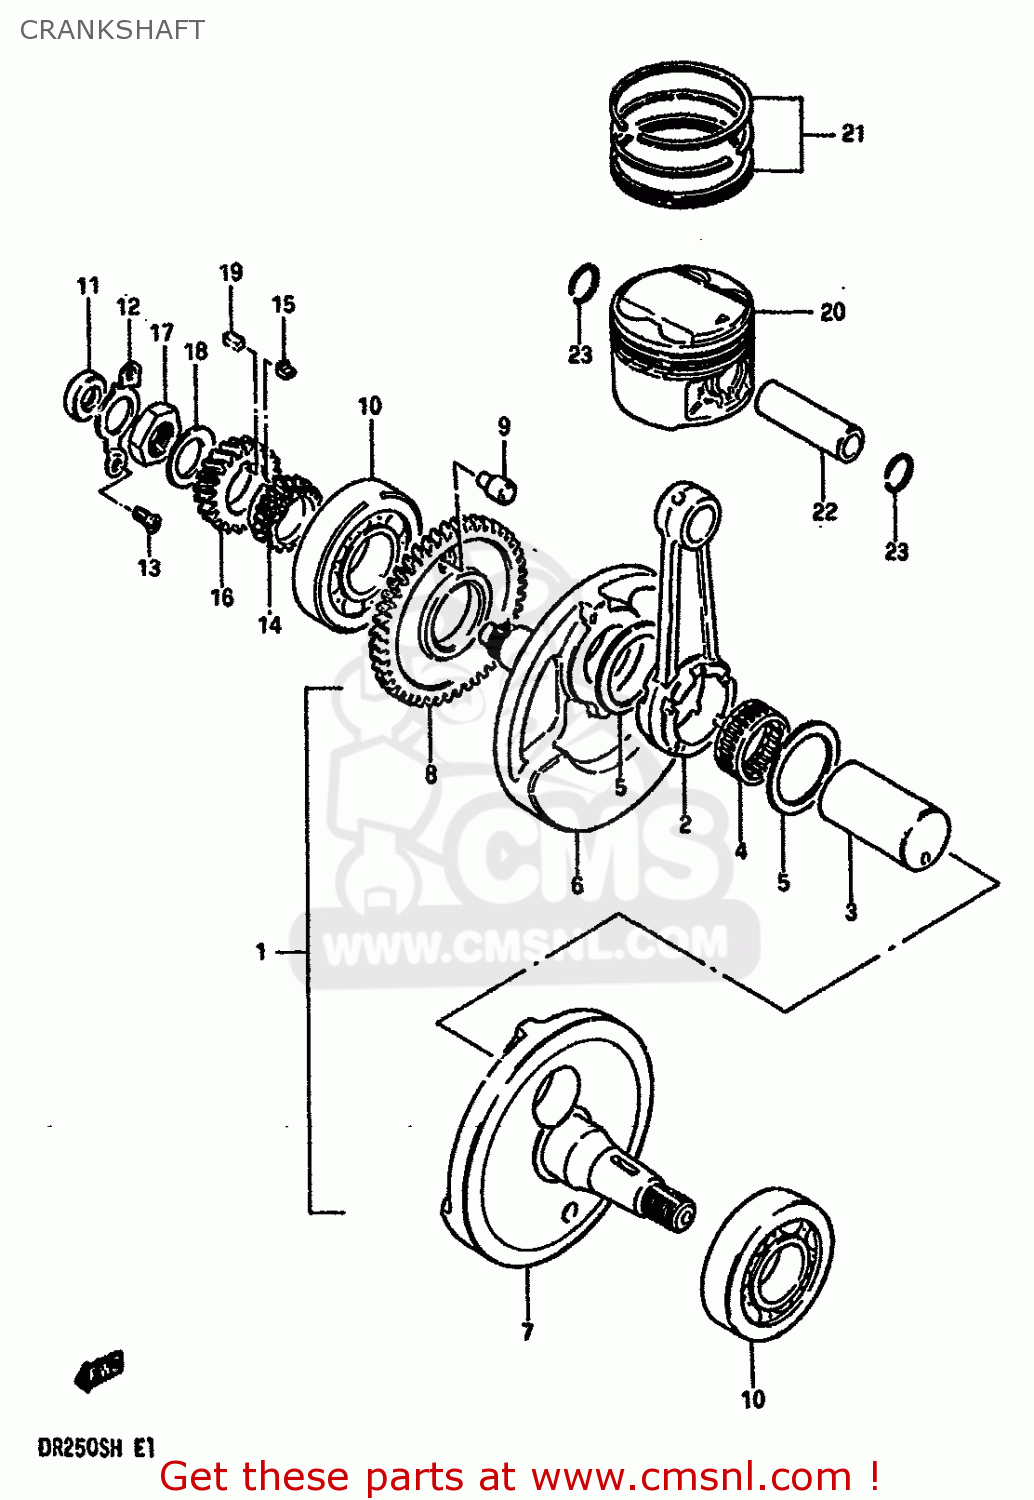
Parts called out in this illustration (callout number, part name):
1	CRANKSHAFT ASSEMBLY
2	ROD,CONNECTING
3	PIN,CRANK
4	BEARING
5	WASHER(31X48.5X1)
6	CRANKSHAFT,R
7	CRANKSHAFT,LEFT
8	GEAR,CRANK BALANCER DRIVE
9	PIN
10	BEARING(30X72X19)
11	SEAL,OIL(14X26X6)
12	RETAINER,CRANKSHAFT BEARING,R
13	SCREW
14	SPROCKET,CAM CHAIN DRIVE(NT:21
15	KEY,SPROCKET
16	GEAR,PRIMARY DRIVE NO.21
17	NUT (20MM)
18	WASHER
19	KEY
20	PISTON
21	RING SET,PISTON
22	PIN,PISTON
23	CIRCLIP,PISTON PIN
